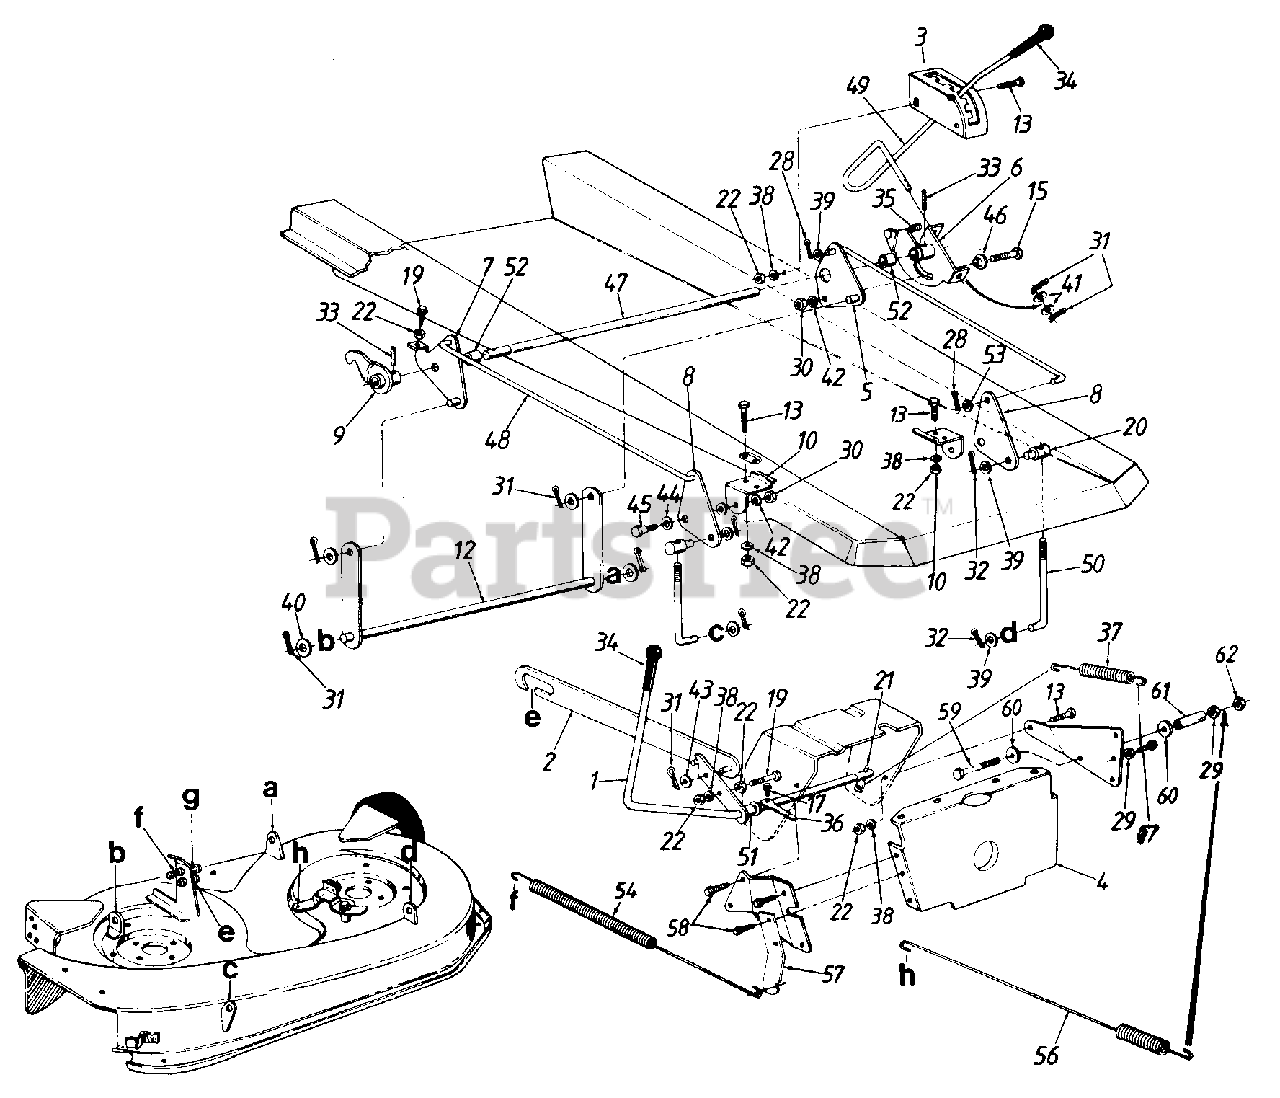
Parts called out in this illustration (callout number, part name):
1	Blade Engagement Lever Ass'y.
6	Deck Lift Handle Retainer Ass'y.
7	Deck Lift Brkt. Ass'y.
8	Deck Lift Bracket
9	Deck Lift Float Brkt Ass'y.
10	Deck Lift Pivot Brkt.
12	Stabilizer Shaft Ass'y.
13	Hex Bolt 5/16-18 x .75" Lg.
15	Hex Bolt 3/8-16 x 1" Lg.
17	Hex Wash. Hd. Scr. 1/4-20 x 1.5" Lg.
19	Hex Wash.-Tap Scr. 5/16-18 x 1.25" Lg.
20	Ferrule
21	Clevis Pin
22	Hex Nut 5/16-18 Thd.
28	Cotter Pin 3/32" Dia.
29	Hex Nut 1/4-20 Thd.
30	Hex Nut 3/8-16 Thd.
31	Internal Cot. Pin 1/2" Dia.
32	Int. Cot. Pins 3/8" Dia.
33	Spring Pin Spir. 1/4" Dia.
35	Compression Spring 1.04"
36	Switch Actuator
37	Ext. Spring 5.86" Lg.
38	L-Wash 5/16" I.D.
39	Fl-Wash. .385 I.D. x .62
40	Fl-Wash. .635 I.D. x 1.12
41	Fl-Wash. .531 I.D. x .930
42	L-Wash. 3/8" I.D.
43	Fl-Wash. .385 I.D. x .87 O.D.
44	Spring Washer .530 I.D.
45	Shld. Bolt .500" Dia. x .215
46	Shld. Spacer .625" I.D.
47	Rear Hgt. Adj. Shaft
50	J-Bolt 5.4" Lg.
51	Spacer. 511 I.D.
52	Spacer .885 I.D.
53	Fl-Wash. 5/16" I.D.
54	Ext. Spring 22.05" Lg.
56	Ext. Spring 15-5/8" Lg.
57	Spring Anchor
58	Hex Wash. Hd. AB-Tap Scr. 1/4 x.62" Lg.
59	Hex Bolt 1/4-20 x 2.5" Lg.
60	Fl-Wash. .25" I.D. x .93" O.D.
61	Spacer.255" I.D.
62	Hex L-Nut 1/4-20 Thd.
